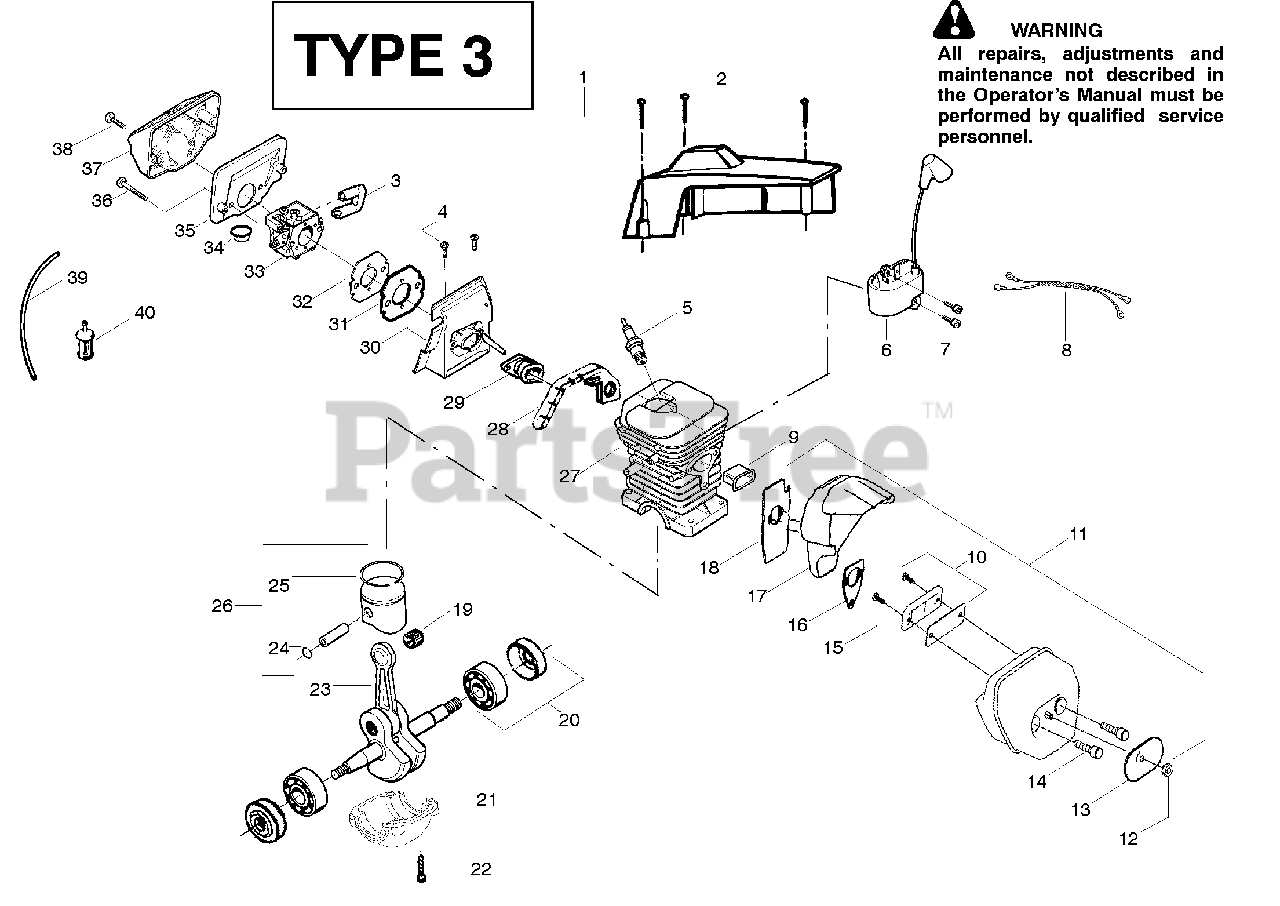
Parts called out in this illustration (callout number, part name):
2	Kit-Cylinder Shield
3	Grommet -Carb.
5	Spark Plug (RCJ-7Y)
6	Module-Ignition
8	Assy-Switch Wire
9	Insulator-Heat
10	Kit-Spark Arrestor
11	Kit-Muffler
12	Nut-Brass
15	Screw-Spark Screen
16	Gasket-Muffler
17	Assy-Muffler Backplate
18	Backplate - Alum.
20	Assy-Bearing & Seal
21	Cap-Crankcase
23	Assy-C’shaft & Rod
24	Retainer-Piston Pin
26	Kit-Piston
27	Assy-Cyl/Crankcase
28	Seal-Super Clean
29	Intake Boot
30	Adapter-Carb.
31	Intake Plate-Carb
33	Kit-Carburetor (WT-610)
35	Filter-Air (Bottom)
37	Filter-Air (Top)
39	Kit-Fuel Line (Small)
40	Assy-Fuel Pick-up
